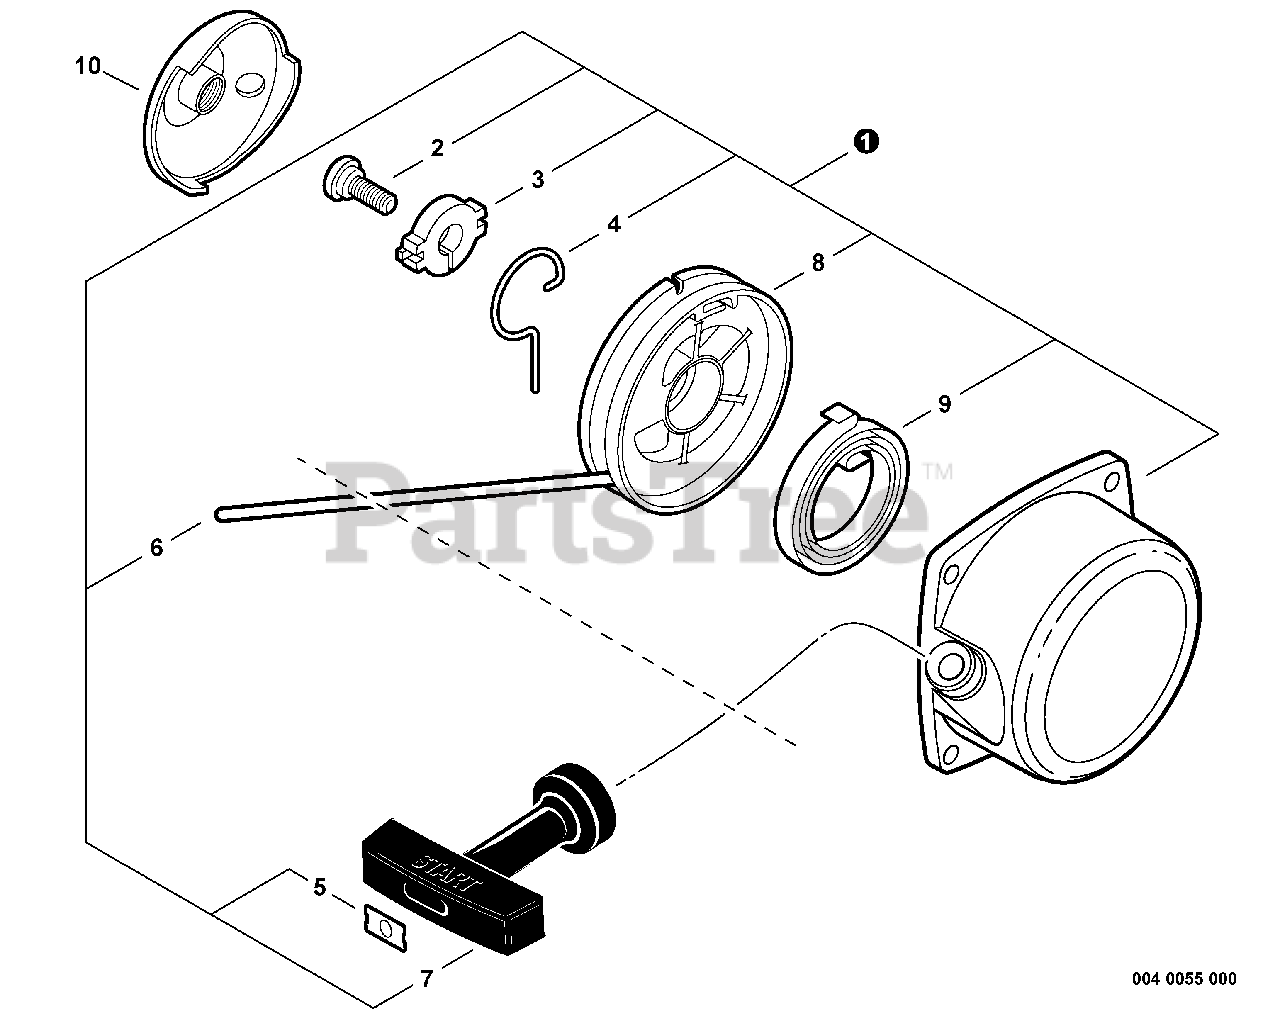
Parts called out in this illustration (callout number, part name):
1	STARTER ASSY
2	SCREW - 5
3	RETAINER, PAWL
4	PAWL, STARTER
5	RETAINER, ROPE
6	ROPE, STARTER
7	GRIP, STARTER
8	REEL, ROPE
9	SPRING, REWIND
10	CATCHER, PAWL
